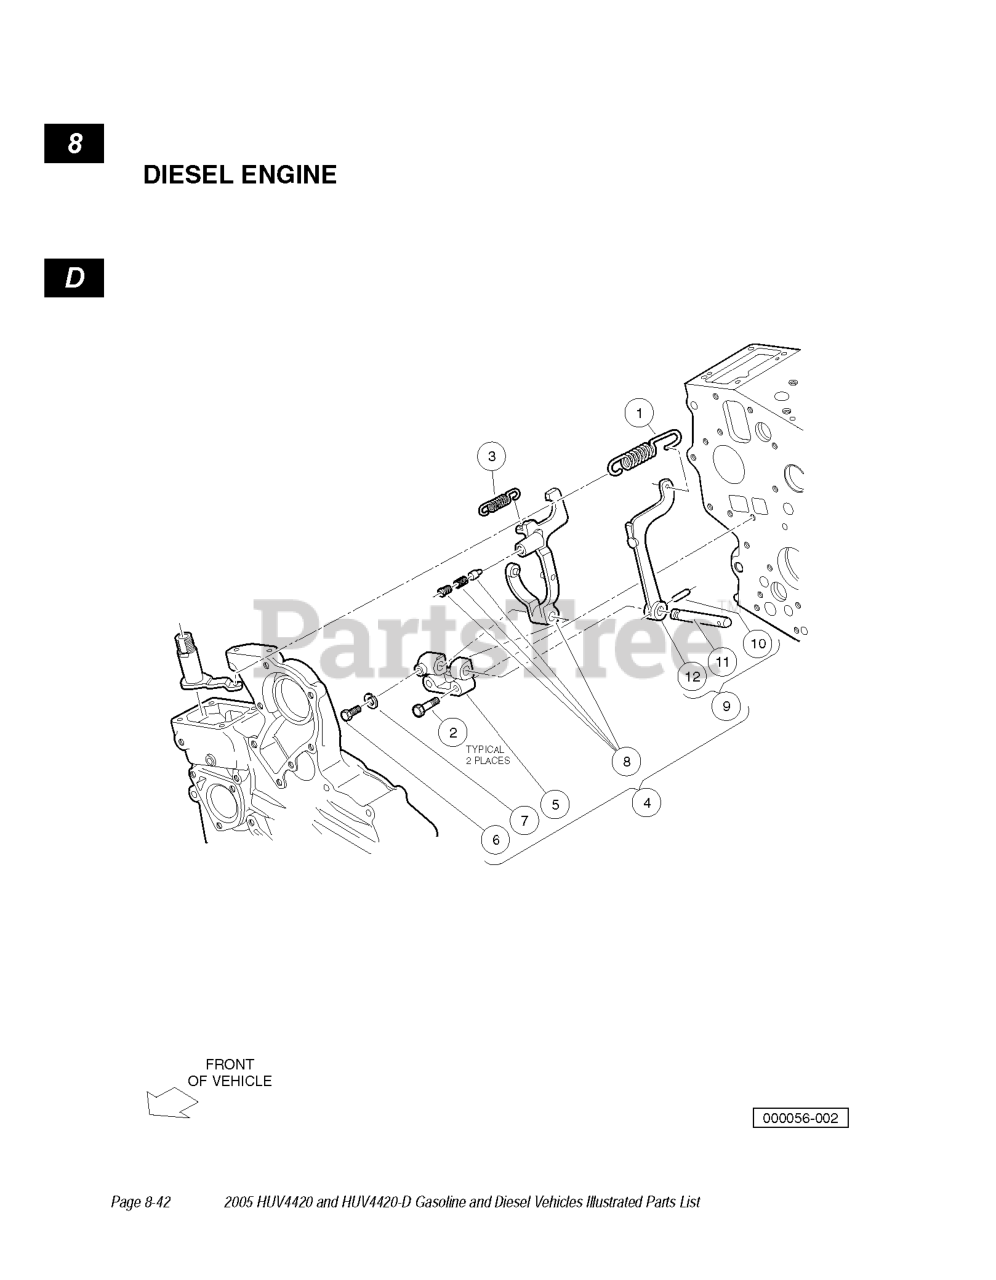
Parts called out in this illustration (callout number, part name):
1	SPRING, GOVERNOR
2	BOLT, M5X0.75X25
3	SPRING-START
4	ASSY, GOV FORK, D722 CB
5	HOLDER, FORK LEVER
6	BOLT, M5X0.75X11
7	WASHER, SPRING, M5
10	PIN, SPRING
11	SHAFT, FORK LEVER
